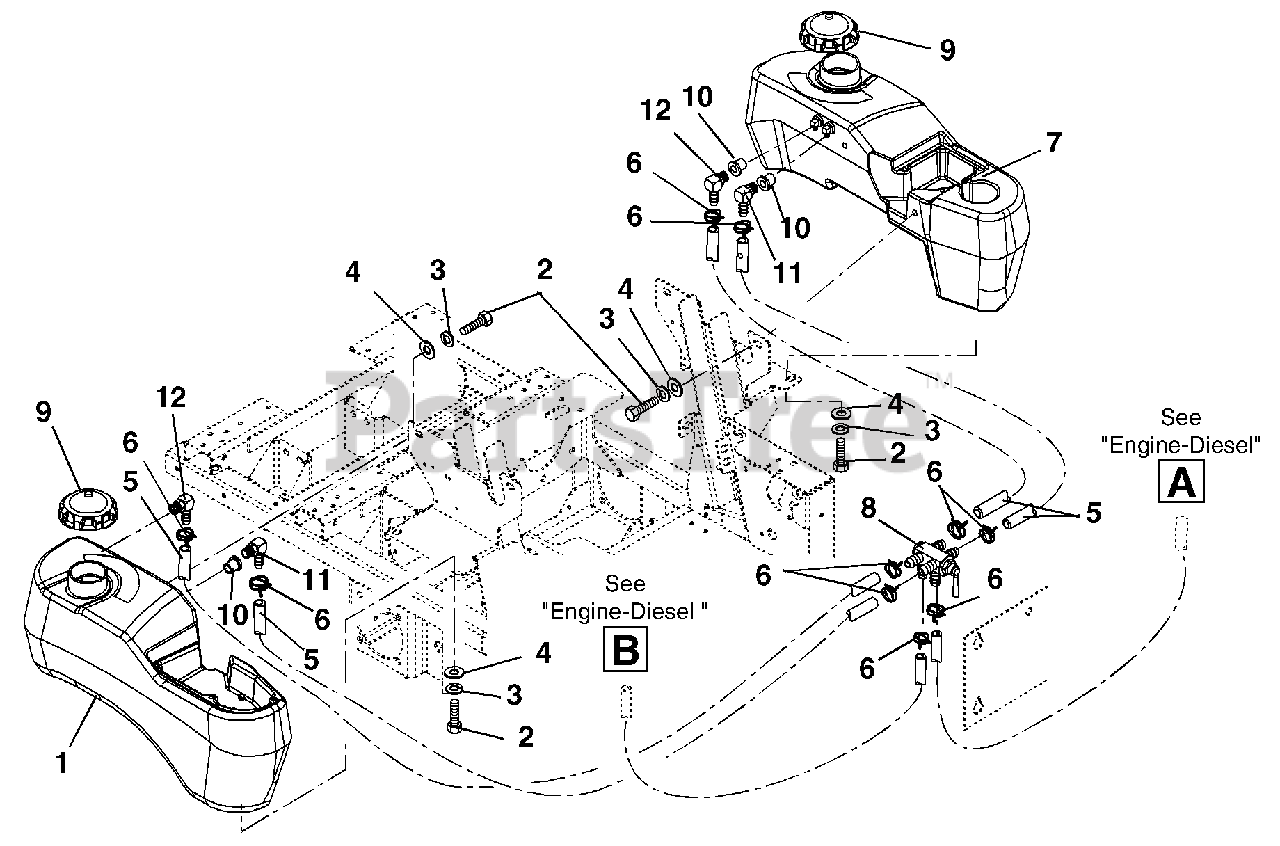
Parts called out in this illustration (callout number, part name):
1	Tank, Fuel-Right Hand (075, 076, 318, 319)
1	Tank, Gas Fuel-Right Hand (073, 074)
2	Bolt, Hex .31-18 x .75 Grade 5
3	Washer, Locking .31 x .078
4	Washer, Flat Steel .38 x .875 x .083
5	Hose, .31 ID (075, 076, 318, 319)
5	Gas Line-Bulk .25 I.D. (073, 074)
6	Clamp, Hose Wire .52/.55 (075, 076, 318, 319)
6	Clamp, Hose Wire .49/.51 x .116 (073, 074)
7	Tank, Left Hand Fuel (EYE-Q) 200 Series-EFI (075, 076, 318, 319)
7	Tank, Left Hand Fuel (EYE-Q) 200 Series (073, 074)
8	Valve, Fuel (075, 076, 318, 319)
8	Valve, Fuel (073, 074)
9	Cap, Fuel (075, 076, 318, 319)
9	Cap, Gas (073, 074)
11	Fitting, Tank (075, 076, 318, 319)
11	Fitting, Tank (073, 074)
12	Fitting, Tank (075, 076, 318, 319)
